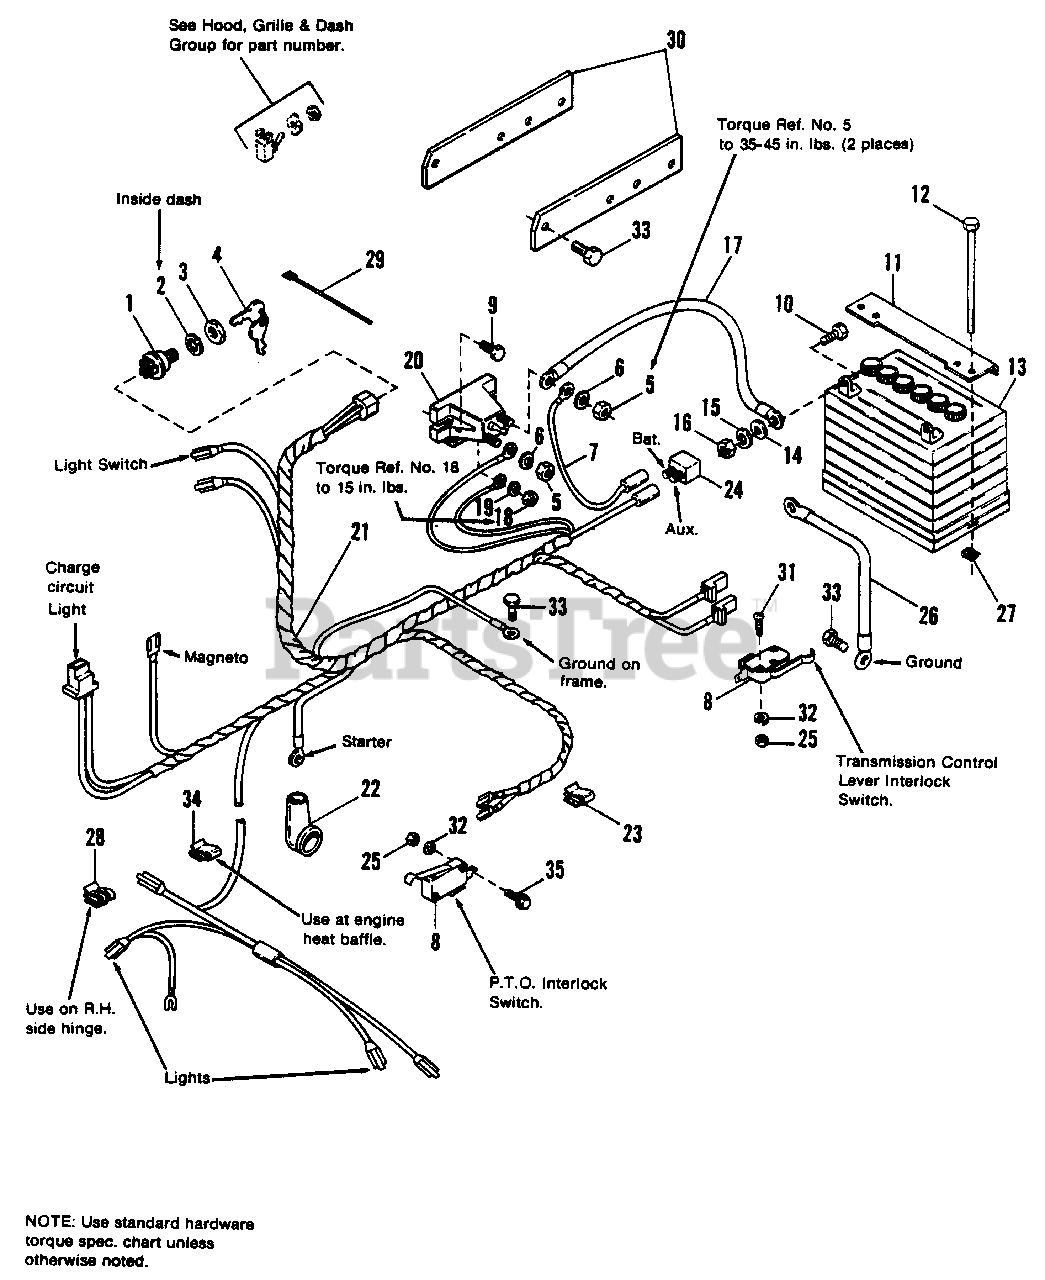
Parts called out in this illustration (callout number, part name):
1	SWITCH, Ignition
2	LOCKWASHER, Internal Tooth, 5/8
3	NUT, 5/8-32
4	KEYS, Set of 2
5	NUT, Hex, 5/16-18
6	LOCKWASHER, 5/16
8	SWITCH, Interlock
9	SCREW, Taptite, 1/4-20 x 5/8
10	CAPSCREW, Hex, 1/4-20 x 3/4
11	CLAMP, Battery
12	CAPSCREW, Hex, 1/4-20 x 7
13	BATTERY SERVICE KIT, 39 Amp.
14	WASHER, 1/4
15	LOCKWASHER, 1/4
16	NUT, Hex, 1/4-20
18	NUT, Hex, #10-32
19	LOCKWASHER, Ext. #10
20	SOLENOID
21	HARNESS, Wiring
22	COVER, Terminal
23	CLIP, Speed
24	CIRCUIT BREAKER
25	NUT, Hex, #5-40
27	NUT, Retainer, 1/4-20
28	WIRE CLIP
29	TIE, Self-Locking
30	BRACE, Shift Panel
31	SCREW, Rd. Hd., Phil #5-40 x 3/4
32	LOCKWASHER, #5
33	SCREW, Taptite, 1/4-20 x 3/8
34	WIRE CLIP
35	SCREW, Taptite, #5-40 x 3/4
